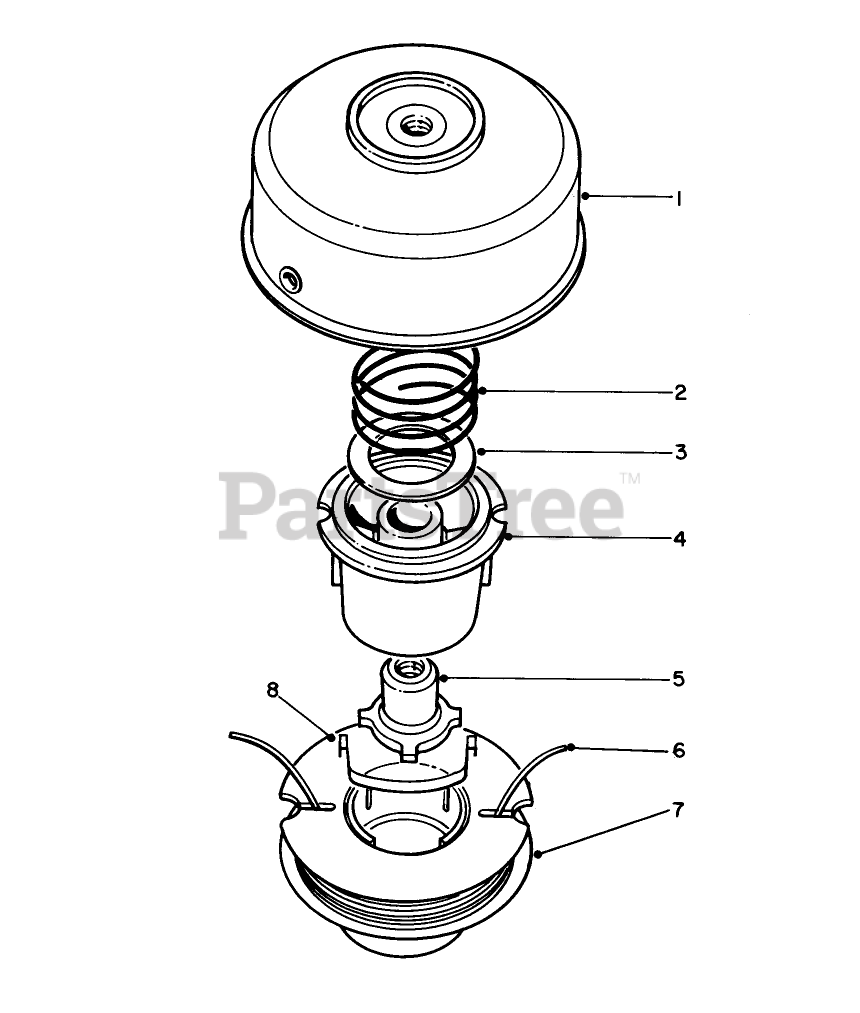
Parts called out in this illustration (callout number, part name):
1	ASM - TRIMMER DRUM & EYELET
2	SPRING
3	WASHER-FLAT
4	SPOOL CORE
5	LH DRIVER
6	REPL LINE PKG
7	Spool Housing
8	SADDLE-SPOOL CAP
